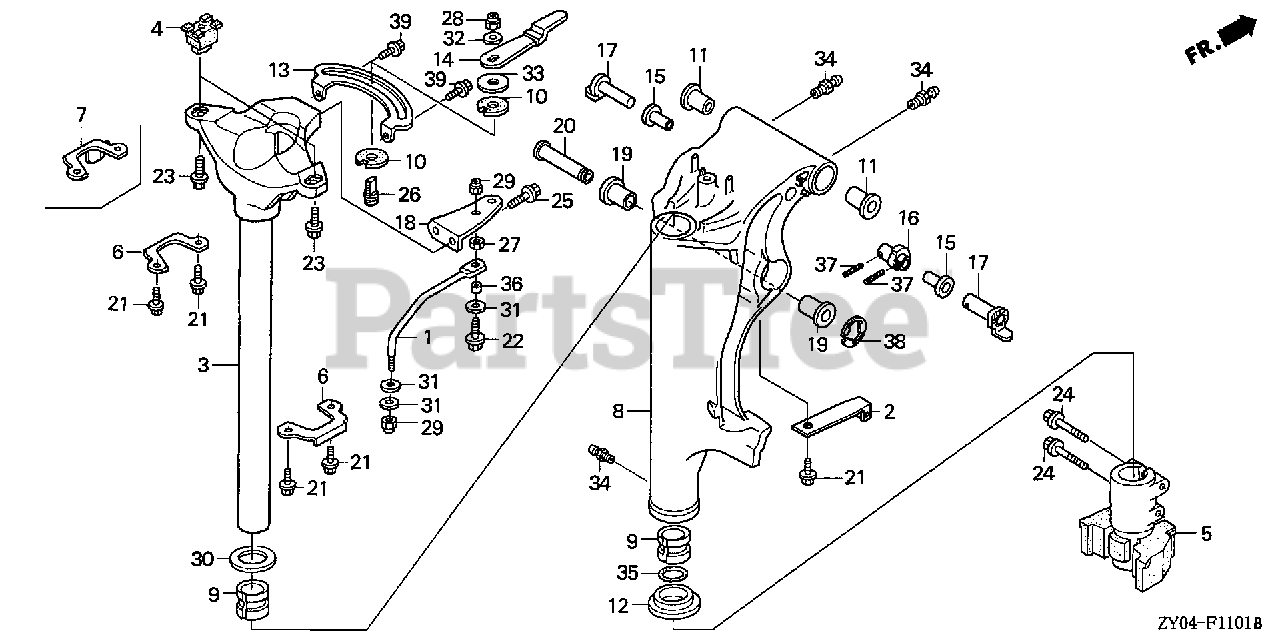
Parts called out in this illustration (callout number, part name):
2	SPRING, CLICK
3	FRAME, MOUNTING (S)
4	RUBBER, MOUNTING (UPPER)
5	RUBBER, MOUNTING (LOWER)
6	COVER, MOUNTING RUBBER (UPPER)
7	COVER, MOUNTING RUBBER (UPPER) (PT)
8	CASE, SWIVEL *NH282MU* (S)(PT) (OYSTER SILVER METALLIC-U)
9	LINER, SWIVEL CASE
10	BLOCK, FRICTION
11	BUSH, SWIVEL CASE
12	COLLAR, SWIVEL CASE
13	PLATE, FRICTION
14	LEVER, FRICTION
15	BUSH, TILT ARM
16	BRACKET, TILTING
17	STOPPER, TILT
19	BUSH, CYLINDER (LOWER)
20	PIN, CYLINDER (UPPER)
21	BOLT, FLANGE (6X12)
23	BOLT, FLANGE (10X25)
24	BOLT, FLANGE (8X45)
26	BOLT, STUD (8X26)
28	NUT, SELF-LOCK (8MM)
30	WASHER, THRUST
32	WASHER (8MM)
33	WASHER, NYLON (8MM)
34	NIPPLE, GREASE
35	O-RING (34X2.4)
37	PIN, SPRING (2.5X20)
38	E-RING (15MM)
39	BOLT, FLANGE (6X12)
